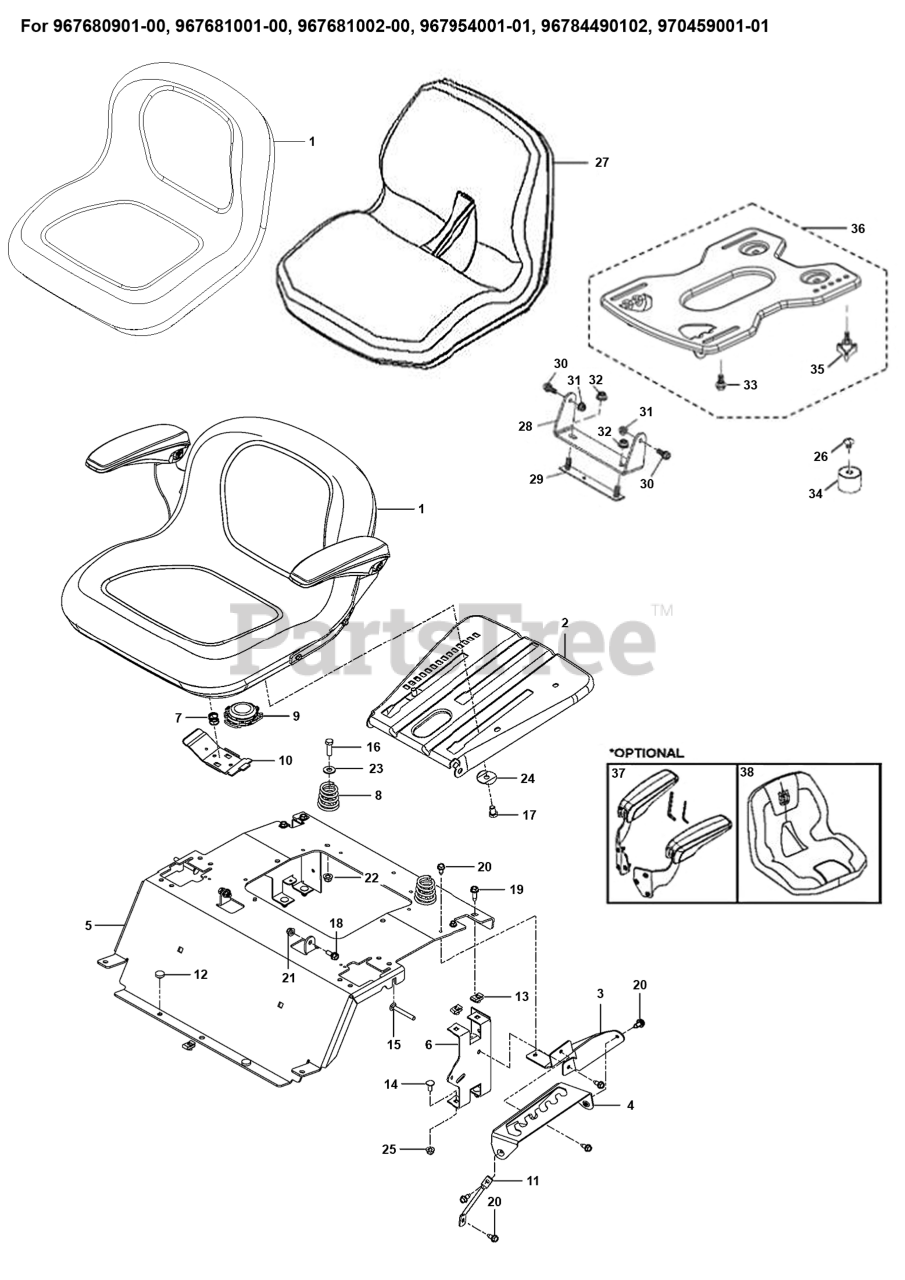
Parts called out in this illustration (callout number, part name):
1	SEAT.TH150.MS498.GRY.HUSQ.TEX
2	PLATE.PNT.SEAT.SLIDE.3PT.EDIP
2	BRACKET SEAT PAN
3	PLATE.SUPPORT.DECK.LIFT.X431
4	PLATE.DECK.LIFT.X431
5	SUPPORT.SEAT.RZ.HUSQ.ORANGE
5	Plates
6	SUPPORT REAR SEAT BLACK
7	SPRING.LATCH.SEAT.TEX
8	SPRING.COMPRESS.SEAT.TAPERED
9	SWITCH.SEAT.DELTA.OPC.
9	SWITCH.SEAT.DP W/RAMPS
9	SWITCH.SEAT.OPC.GRY.BUTTON/CAP
10	HANDLE.SLIDE.SEAT.TEX.BLACK
11	SUPPORT.LEG.DECK.LIFT
12	GROMMET.BUMPER
13	U-CLIP 5/16-18 NUT RETAINER
14	BOLT 5/16C X 3/4" CARRIAGE
15	RHSNB 5/16-18 X 2-1/2 GR5 ZD
16	BOLT
17	BOLT
18	BOLT, SHOULDER
19	SCREW.THDROL.5/16-18X3/4.TTY
19	HHFS 5/16-18 X 3/4
20	BOLT.5/16HEX.WHS.HD
21	5/16-18 NYLOC FLANGE NUT
22	NUT 3/8-16 HEX FLG NYLOC ZD
23	RP WASHER 3/8 FLAT
23	WASHER.WINGED.3/8ID.1.5OD
24	RP WASHER 3/8 FLAT
24	WASHER.WINGED.3/8ID.1.5OD
25	5/16-18 NYLOC FLANGE NUT
26	Hardware
27	Seats
28	Brackets
29	BRACKET ASSEMBLY REINFORCEMENT
30	Bolts
31	NUT HEXAGON FLANGE 5/16-18 ST
32	GSPW Nuts
33	Hardware
34	Bumpers
35	GSPW Knobs
36	Service Kit
37	ARMREST KIT
38	Seats
